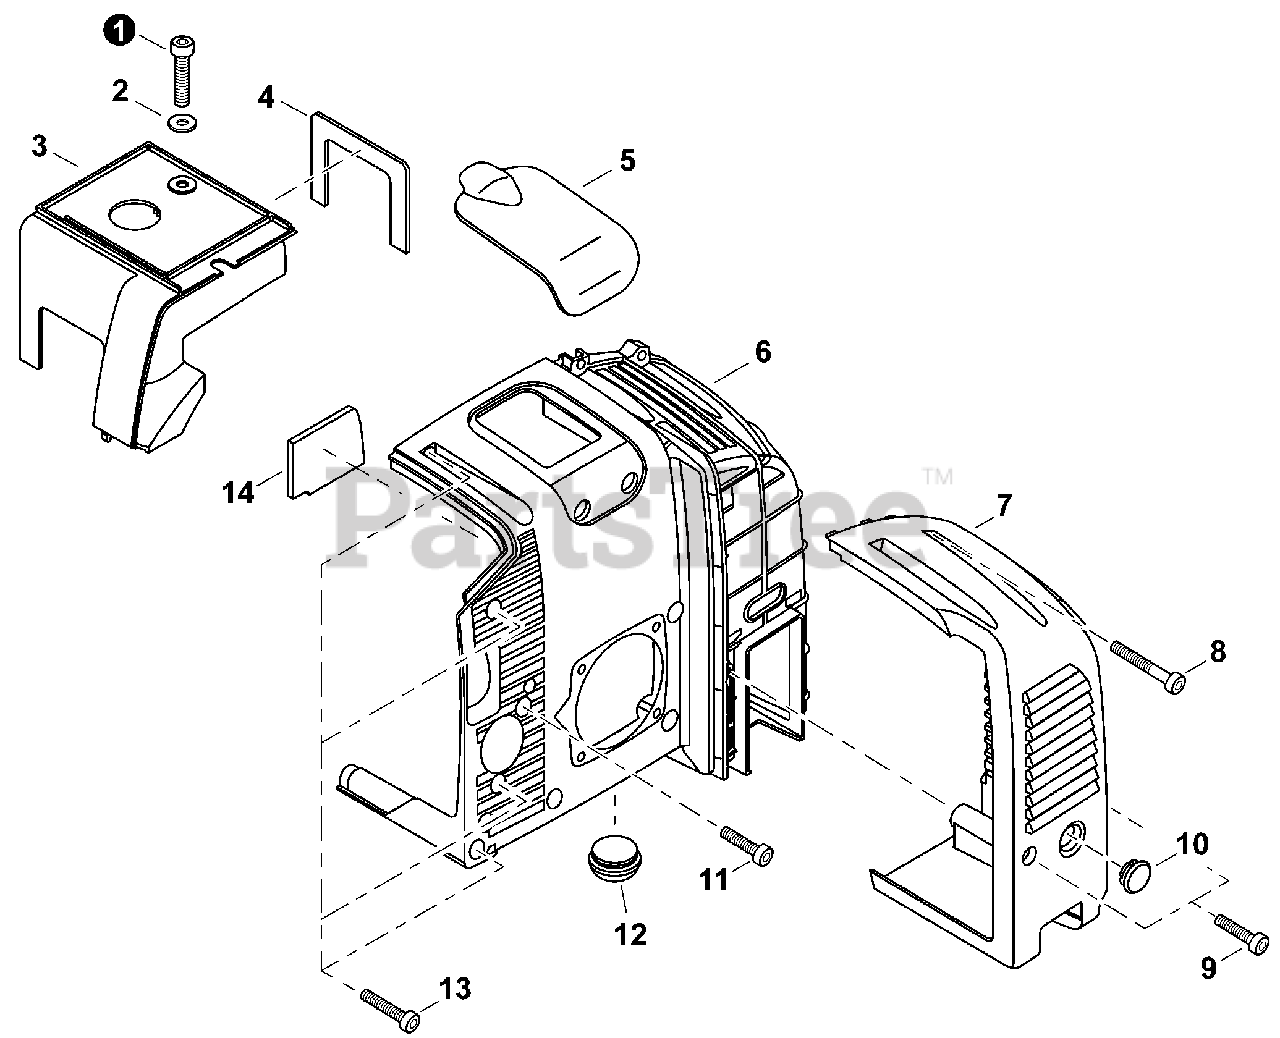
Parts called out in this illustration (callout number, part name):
1	SCREW 5×20
2	WASHER 5.2×14×T3
3	COVER, CYLINDER
4	PLATE, INSULATOR
5	COVER, SPARK PLUG
6	COVER, ENGINE
7	COVER, MUFFLER
8	BOLT, TORX 5×25
9	BOLT, TORX 5×16
11	SCREW 5×16
12	CUSHION
13	BOLT, TORX 5×20
14	PLATE, INSULATOR
